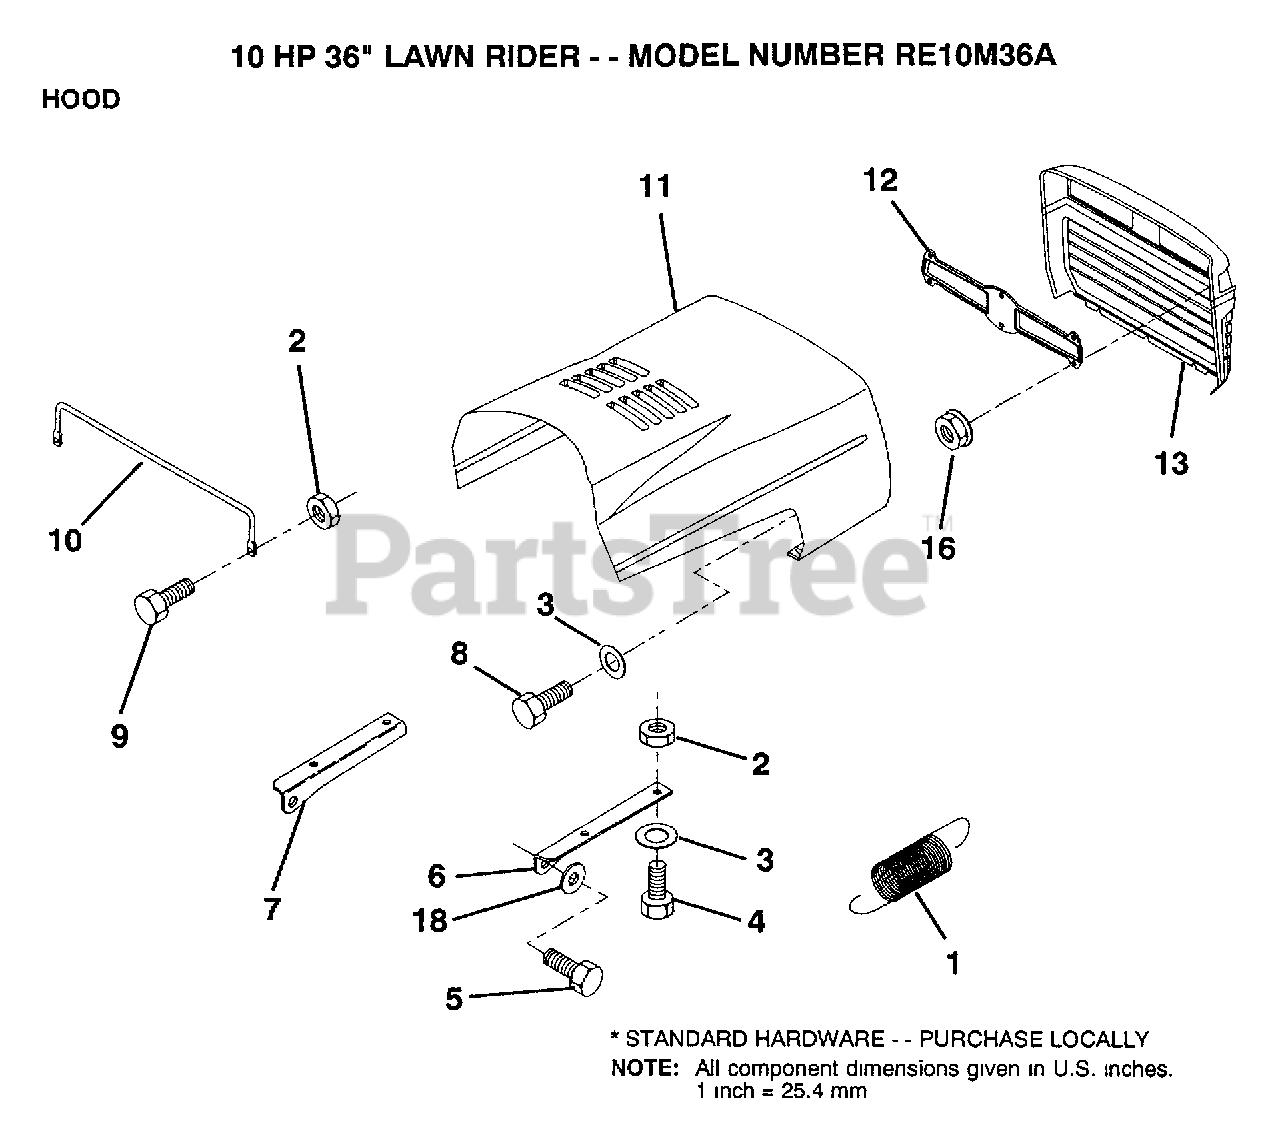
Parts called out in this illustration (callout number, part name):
1	EXT SPRING
2	NUT
3	WASHER
4	BOLT
6	BRKT HOOD RH
7	BRKT HOOD LH
10	"BRACE,HOOD"
11	HOOD
13	GRILL (BLACK)
16	NUT
18	WASHER
